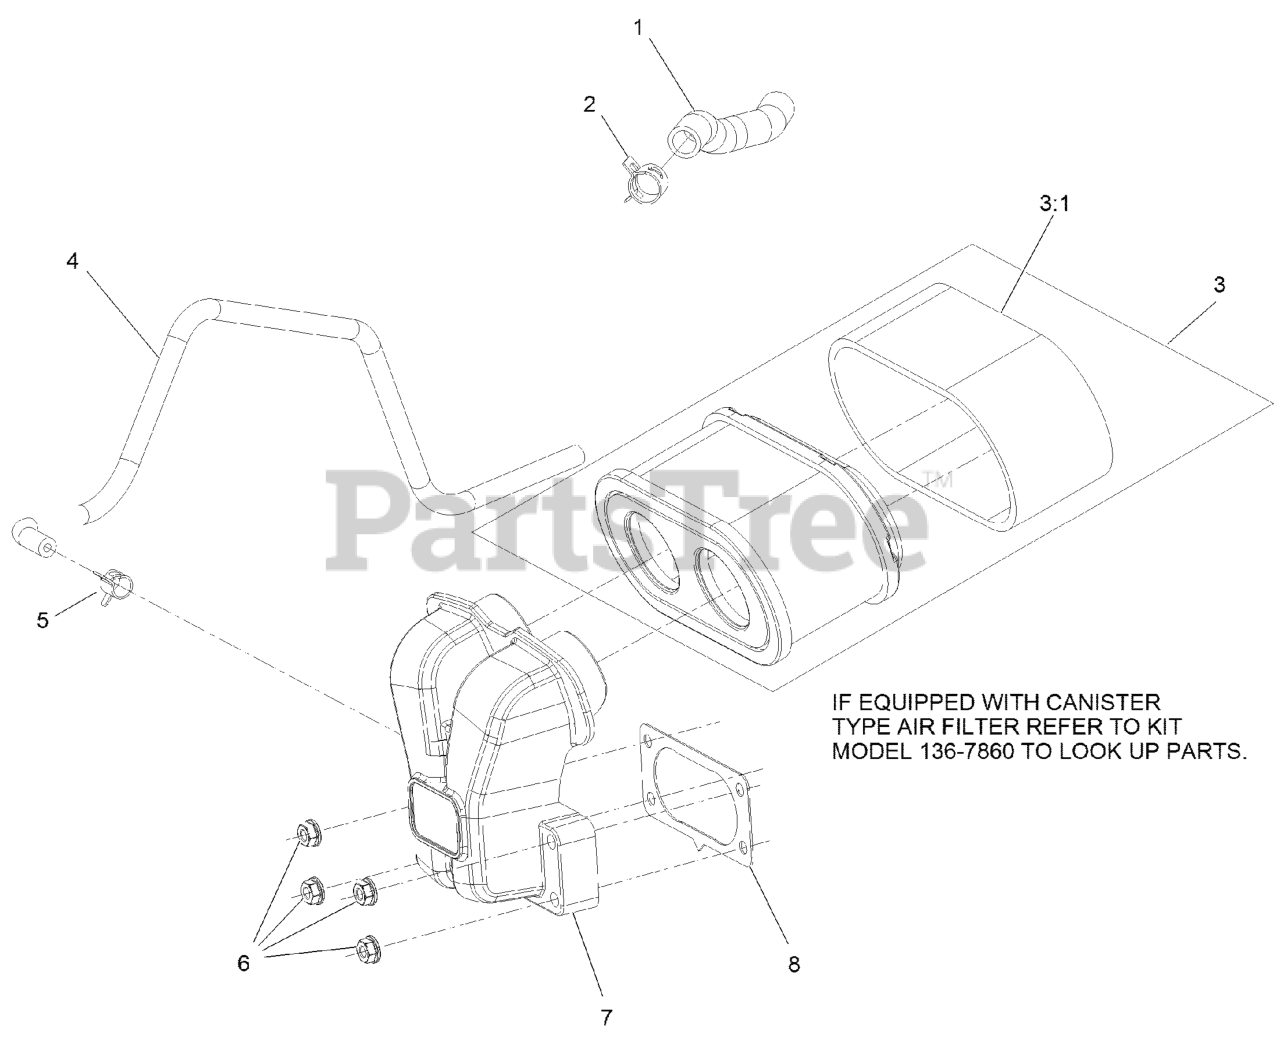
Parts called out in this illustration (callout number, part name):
1	TUBE-BREATHER
2	CLAMP-HOSE
3	AIR FILTER KIT
3:1	PREFILTER
4	HOSE-FUEL
5	CLAMP-HOSE
6	NUT-FLANGE
7	MANIFOLD-FILTER, AIR
8	GASKET-CARBURETOR
